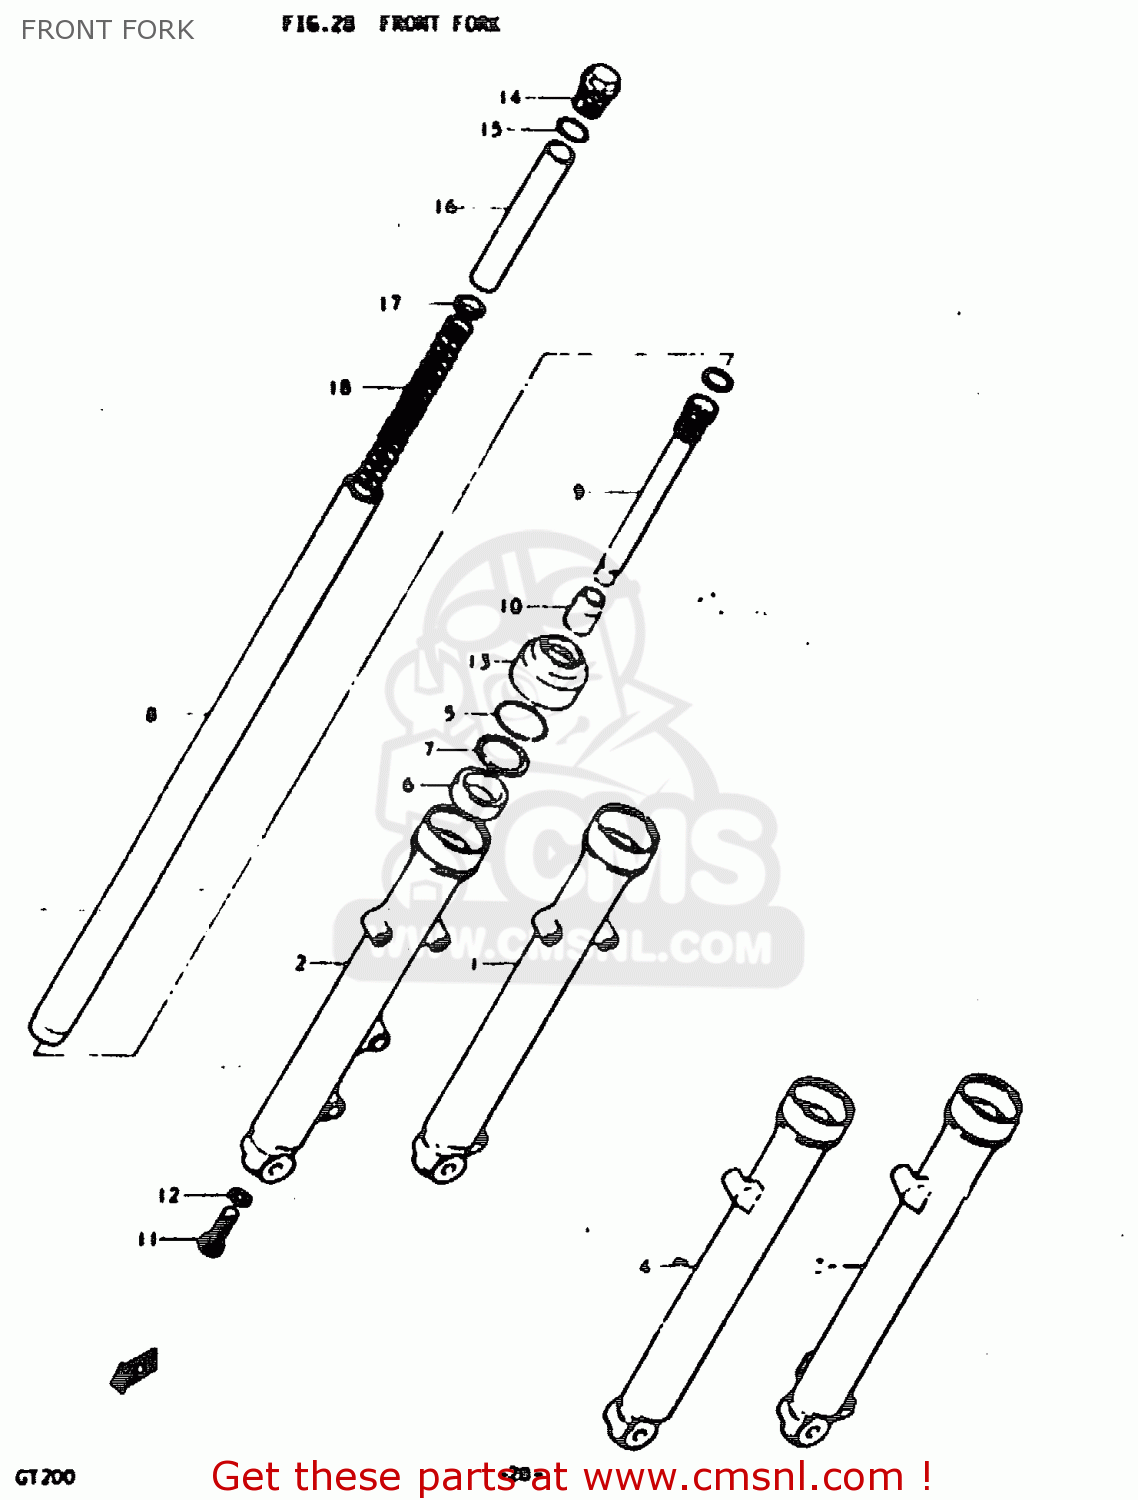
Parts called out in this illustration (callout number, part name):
1	OUTER TUBE, RH
3	OUTER TUBE, LH
5	RING,SNAP
6	OIL SEAL,FRONT FORK
7	WASHER,FRONT FORK
8	INNER TUBE
9	CYLINDER
10	PIECE,OIL LOCK
11	BOLT,FORK CYLINDER(10X25)
12	GASKET (NAS)
13	SEAL,DUST
14	BOLT,FR FORK
15	O-RING,FORK INNER TUBE
16	SPACER
17	GUIDE,SPRING COVER
18	SPRING
